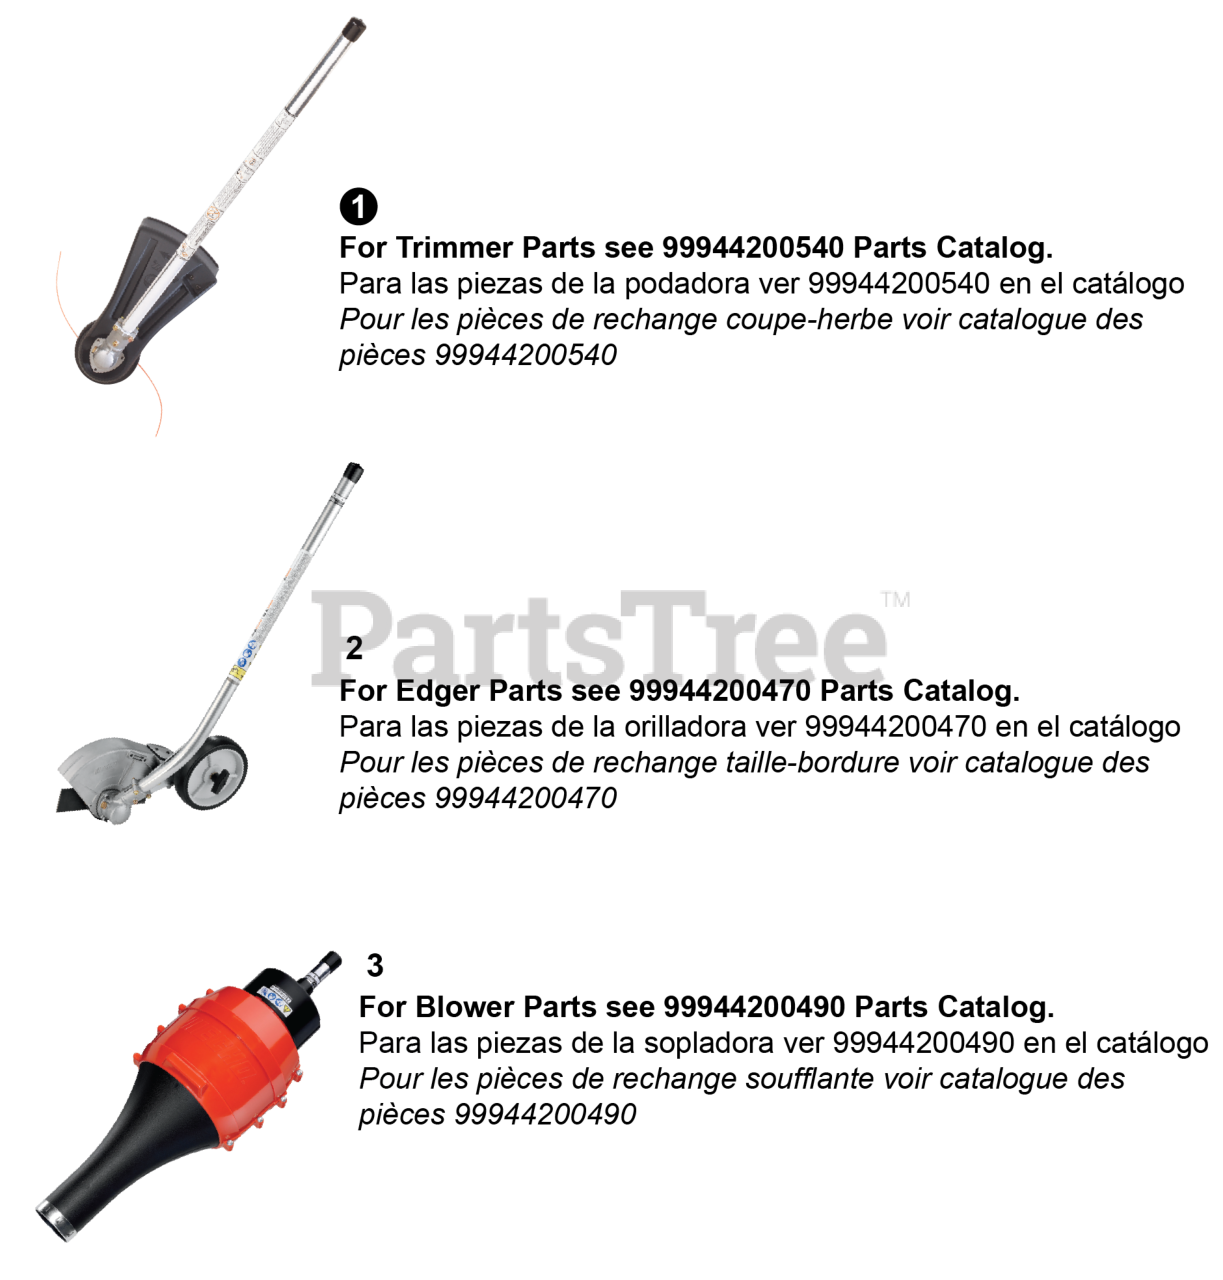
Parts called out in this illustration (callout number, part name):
1	TRIMMER ATTACHMENT
2	EDGER ATTACHMENT
3	BLOWER ATTACHMENT
